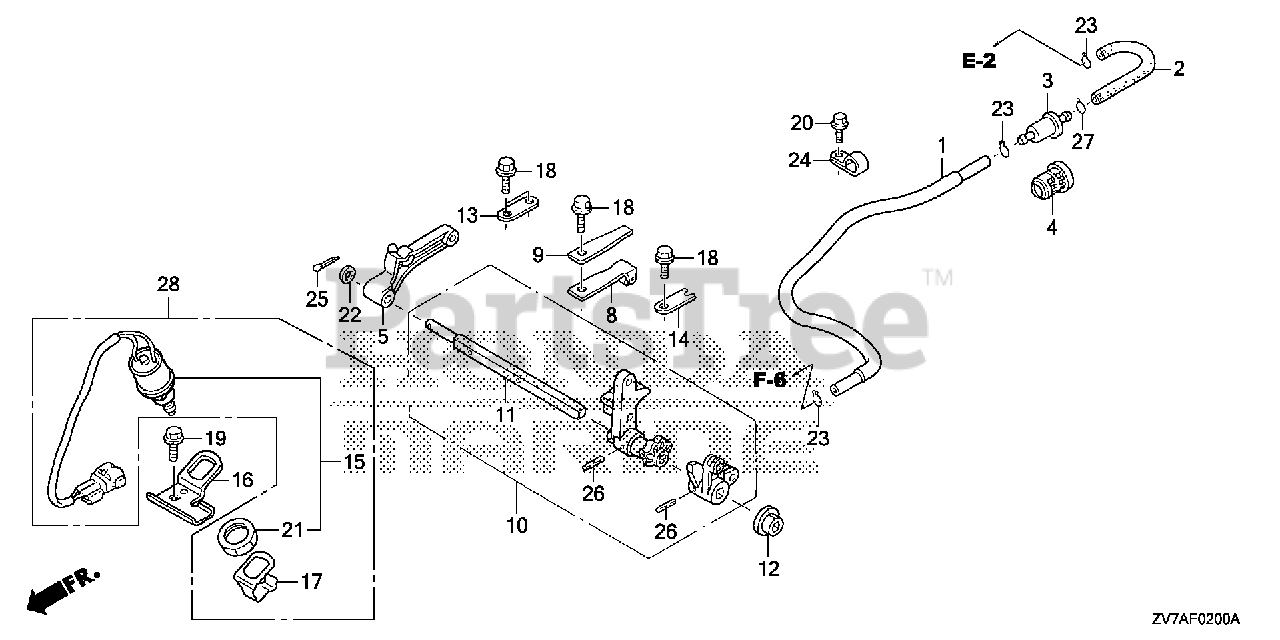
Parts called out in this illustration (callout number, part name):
1	TUBE, FUEL (FKM)
2	TUBE B, FUEL (FKM)
3	FILTER, FUEL
4	SUSPENSION, STRAINER
5	ARM, THROTTLE
8	SPRING, CLICK
9	SPRING, CLICK ASSIST
10	SHAFT, SHIFT
11	SHAFT, SHIFT
12	BUSH, SHAFT
13	PLATE, SHIFT
14	PLATE, SHIFT SHAFT
15	SWITCH ASSY., NEUTRAL
16	BRACKET, NEUTRAL SWITCH
17	PLATE, NEUTRAL SWITCH
18	BOLT, FLANGE (6X12) (CT200)
19	BOLT, FLANGE (6X12) (CT200)
20	BOLT, FLANGE (5X10) (CT200)
21	NUT, HEX. (20MM)
22	WASHER (7.5MM)
23	CLIP, TUBE
24	CLIP (14MM)
25	PIN, SPLIT (2.0)
26	PIN, SPRING (3X20)
27	CLIP, TUBE (B10)
